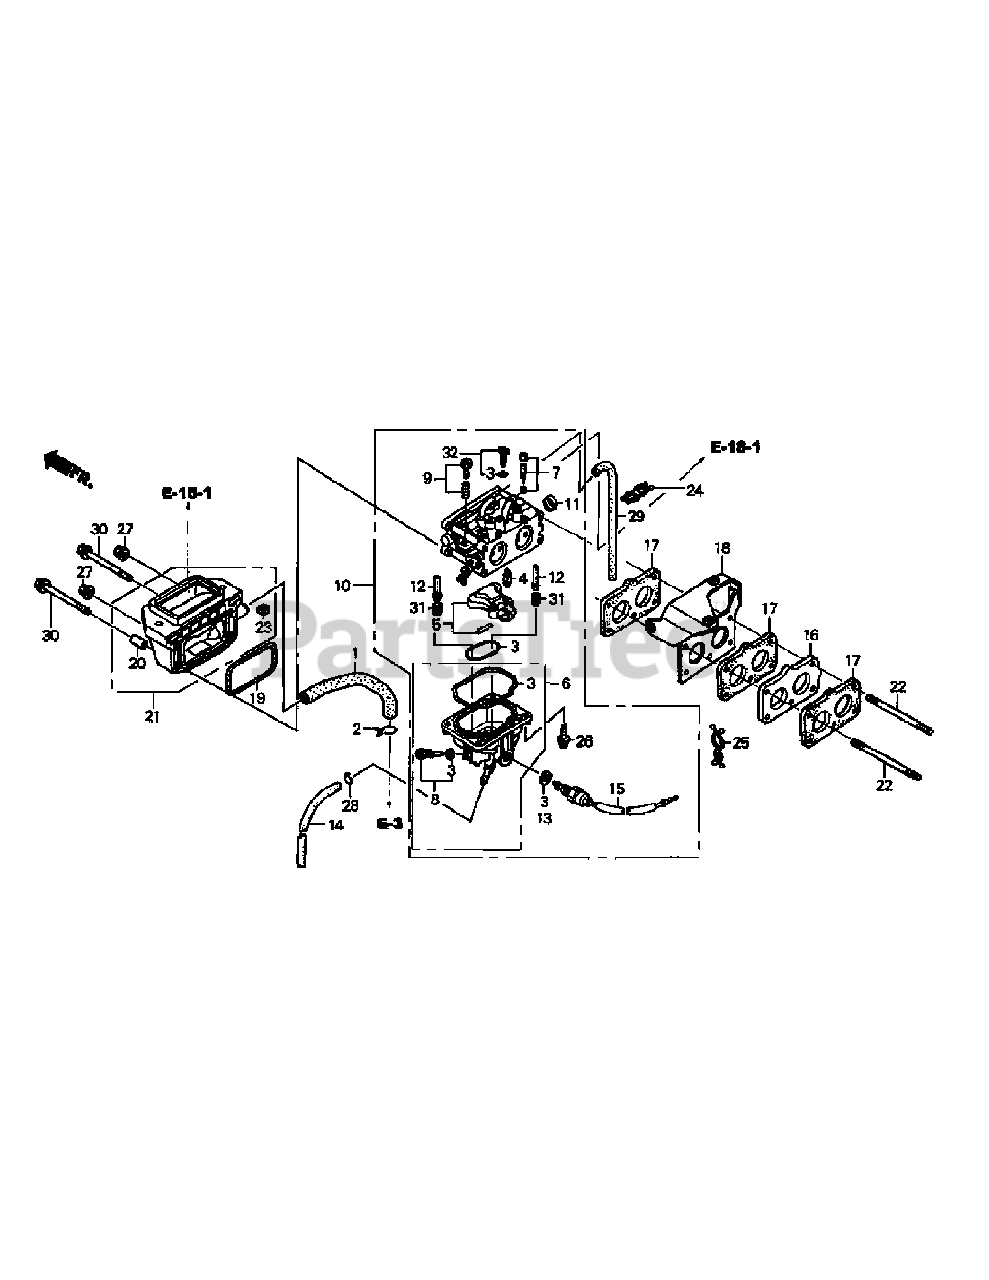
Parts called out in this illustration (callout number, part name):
1	Breather Tube
2	Breather Tube Clip
3	Gasket Set
4	Float Valve Set
6	Float Chamber Set
7	Screw Set (Pilot)
8	Drain Screw Set
10	Carburetor Assy.
11	Choke Lever Dust Cap
12	Main Nozzle
13	Plain Washer
14	Drain Tube
15	Fuel Shut-off Solenoid
16	Carburetor Insulator
17	Carburetor Gasket
18	Fuel Pump Bracket
19	Air Cleaner Gasket
20	Air Cleaner Collar
21	Air Cleaner Elbow
22	Stud Bolt (6x113)
23	Insert Nut (6mm)
24	Wire Harness Clip
25	Purse Lock Clip
26	Pan Screw (4x14)
27	Flange Nut (6mm)
28	Tube Clip
29	Fuel Line (4.5x540)
30	Flange Bolt (6x100)
31	Main Jet Set (#92)
32	Pilot Jet Set (#40)
